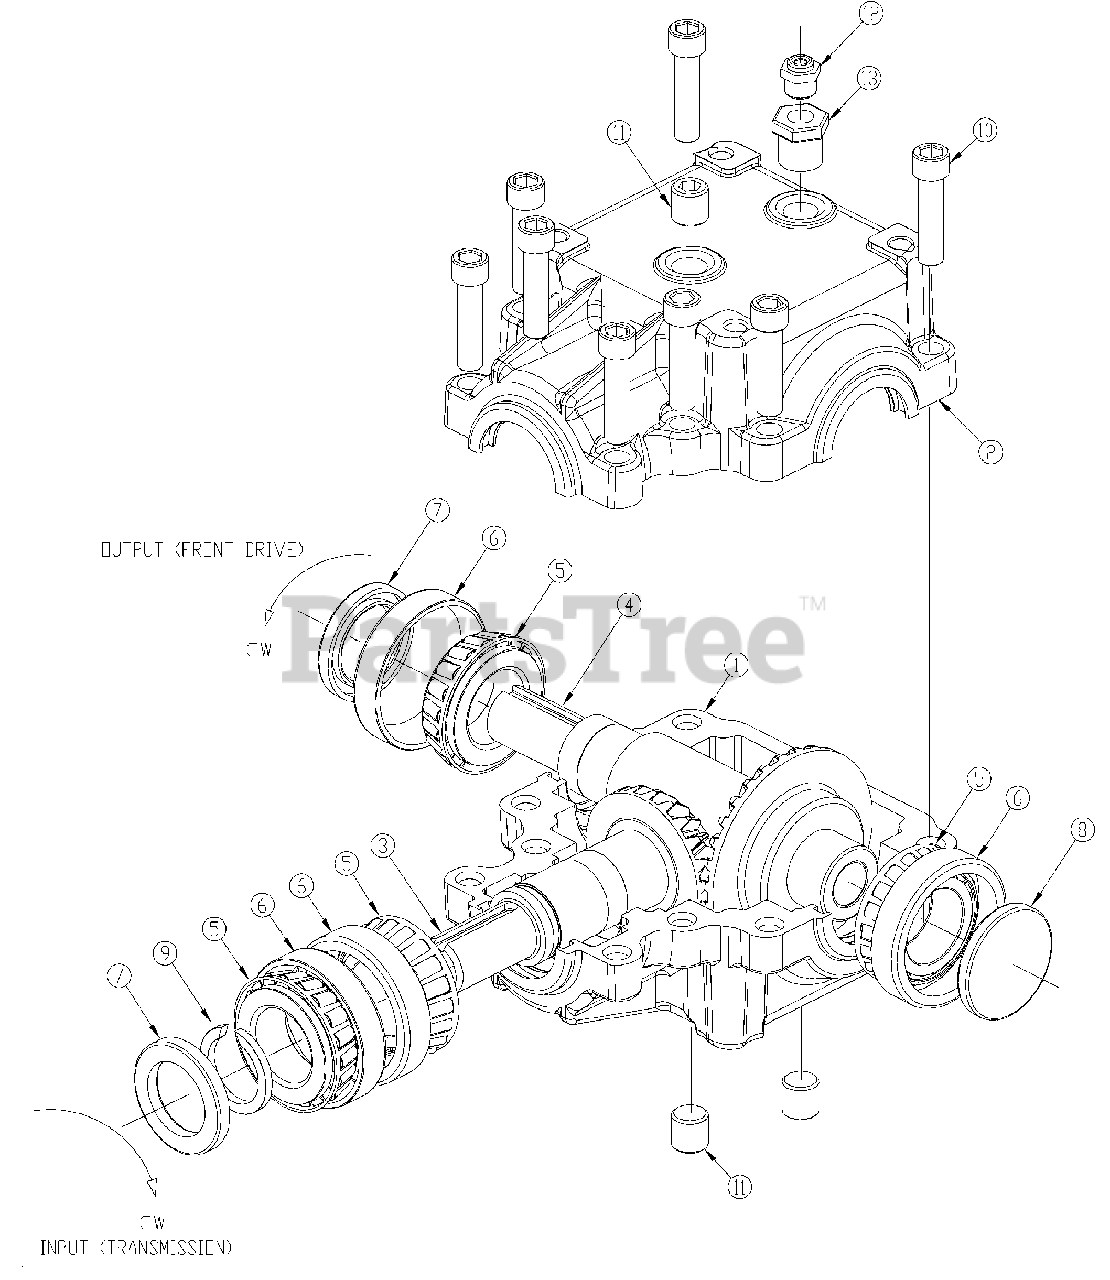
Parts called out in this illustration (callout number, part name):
1	GBOX MODEL R100 1.5TO1 RATIO
1	HOUSING, R100 MACHINED TAP STD
2	HOUSING, R100 MACHINED THRU STD
3	STUB SHAFT/GEAR ASSEMBLY
4	SUPERIOR CROSS SHAFT/GEAR ASSEMBLY
5	BEARING, CONE1.00VN-L44643
6	BEARING, CUP 1.98VN-L44610
7	SEAL, 1-1.5-.187(R)TC
8	CAP, CP-1.5 -.187D#7647
9	RTN RING EXT1.000 SHAFT
10	BOLT 5/16-18 X 1.25 SHCS
11	PLUG 1/4-18NPT SCHD
12	PLUG VENT 5PSIV/N005677
13	BUSHING 1/4NPT X 1/8 NPT
